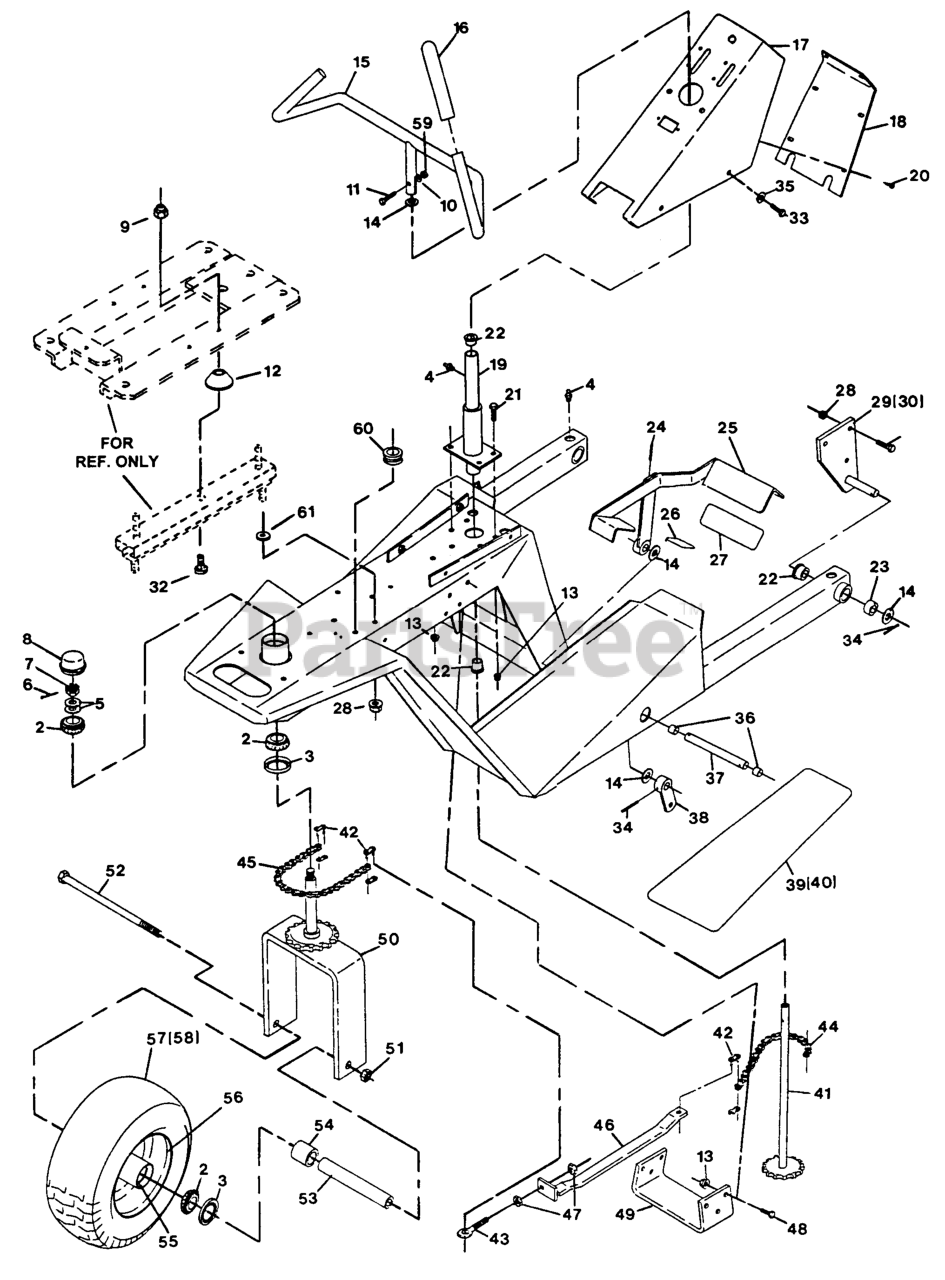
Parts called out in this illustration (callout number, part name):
2	Cone-Bearing Tapered Roller
3	SEAL-GREASE
8	CAP-GREASE
12	SPACER-TRACK
23	SLEEVE,BEARING
24	PIN,ROLL
27	PAD,ANTISKID
29	WLD,BRACKET PIVOT RH
38	WLD,FOOT PEDAL LEVER
39	PAD,ANTISKID RH
43	EYEBOLT, RH
49	STOP,ACTUATOR
52	SCRW,CAP HH
53	BUSHING, WHEEL - PLT
54	SPACER,WHEEL SHORT
55	CUP-BEARING
56	WHEEL 8.00 W/HUB
57	ASM,WHEEL & TIRE
58	TIRE ONLY 8NHS
60	GROMMET
